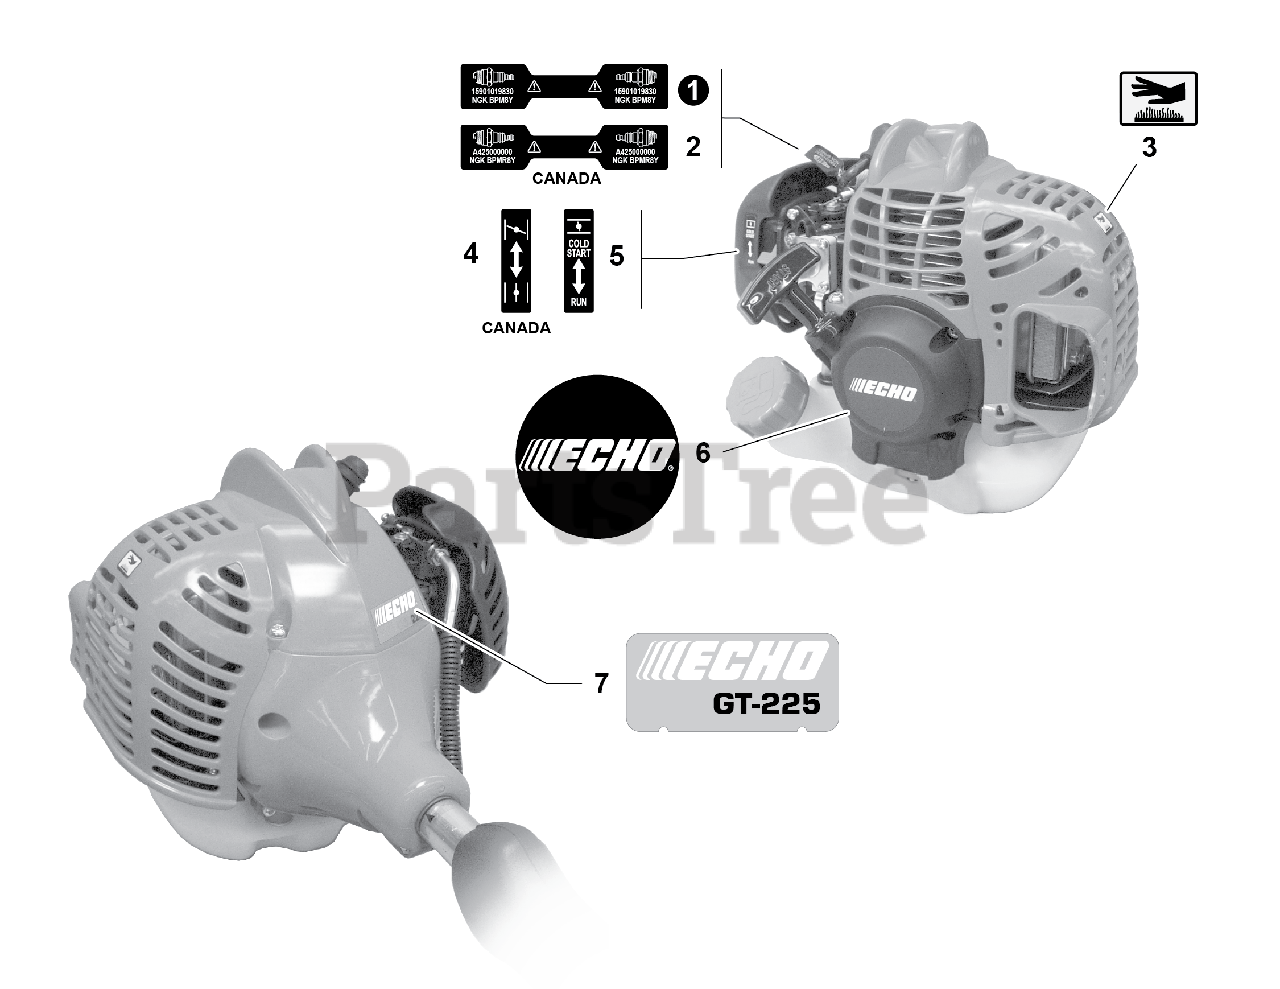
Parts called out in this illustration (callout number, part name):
1	LABEL, SPARK PLUG - BPM8Y
2	LABEL, SPARK PLUG - BPMR8Y
3	LABEL, CAUTION - HOT
4	LABEL, CHOKE
5	LABEL, CHOKE
6	LABEL, ECHO
7	LABEL, MODEL
